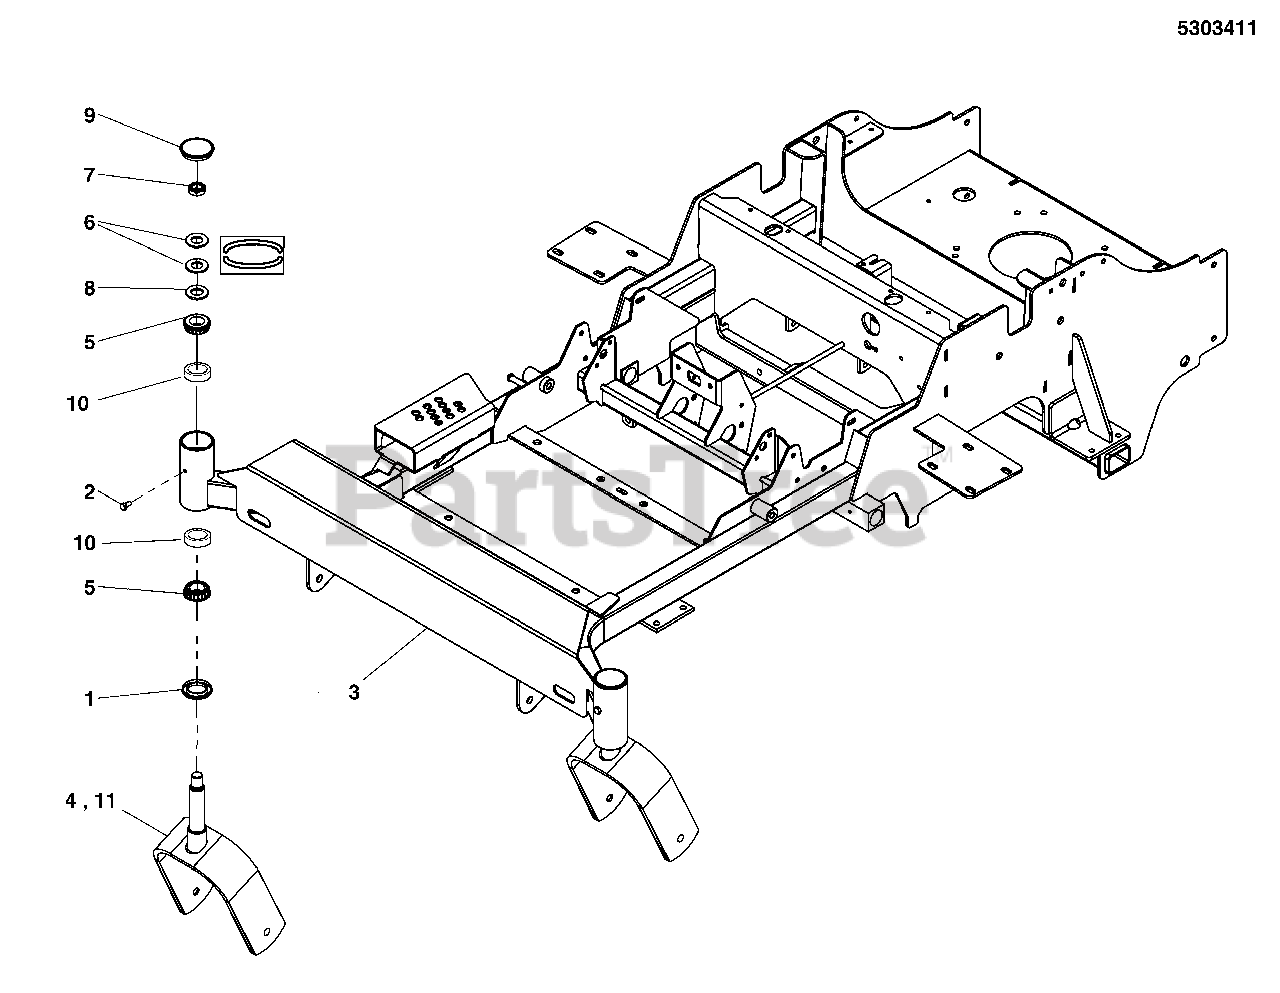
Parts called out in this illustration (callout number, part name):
1	SEAL, GREASE
2	BOLT, 1/4-28 X 1/2, GD5 YZ
3	WELD, MAIN FRAME, 550Z - RED
4	WELD, CASTER YOKE - RED
5	BEARING, TAPERED ROLLER, 1
6	WASHER, BELLEVILLE - 1.500 X .755
7	NUT, 3/4-16, HEX JAM NYLON LOCK
8	WASHER, 3/4 SAE
9	CAP, LOW PROFILE, STEEL
10	BEARING CUP (SV)
11	WELD, CASTER YOKE - RED
